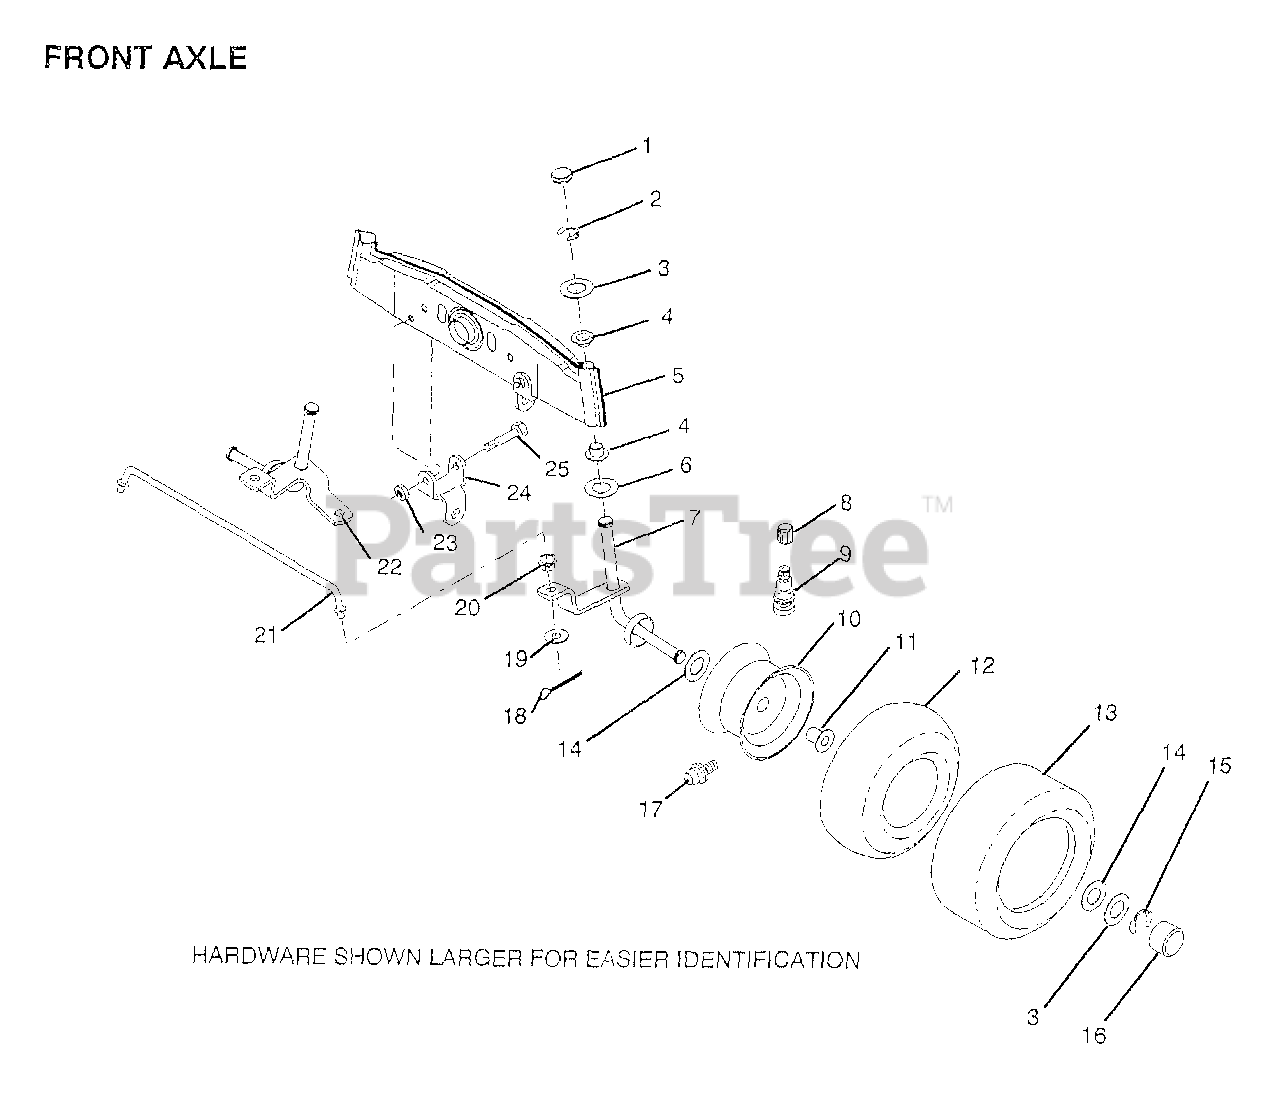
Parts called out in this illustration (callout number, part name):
1	CAP
2	RING
3	WASHER
4	NYLINER
5	AXLE FRONT
6	WASHER .T
7	SPINDLE RH
8	VALVE CAP
9	VALVE STEM LT
11	"FLANGE, BEARING"
12	TUBE.5.3/4.5/6
13	TIRE
14	WASHER
15	RING
16	HUB CAP
17	FITTING LT
18	COTTER PIN
19	WASHER
20	BUSHING.DRAGLINK
21	ROD TIE
22	SPINDLE LH
24	"BRKT,FRONT STAB"
25	BOLT
